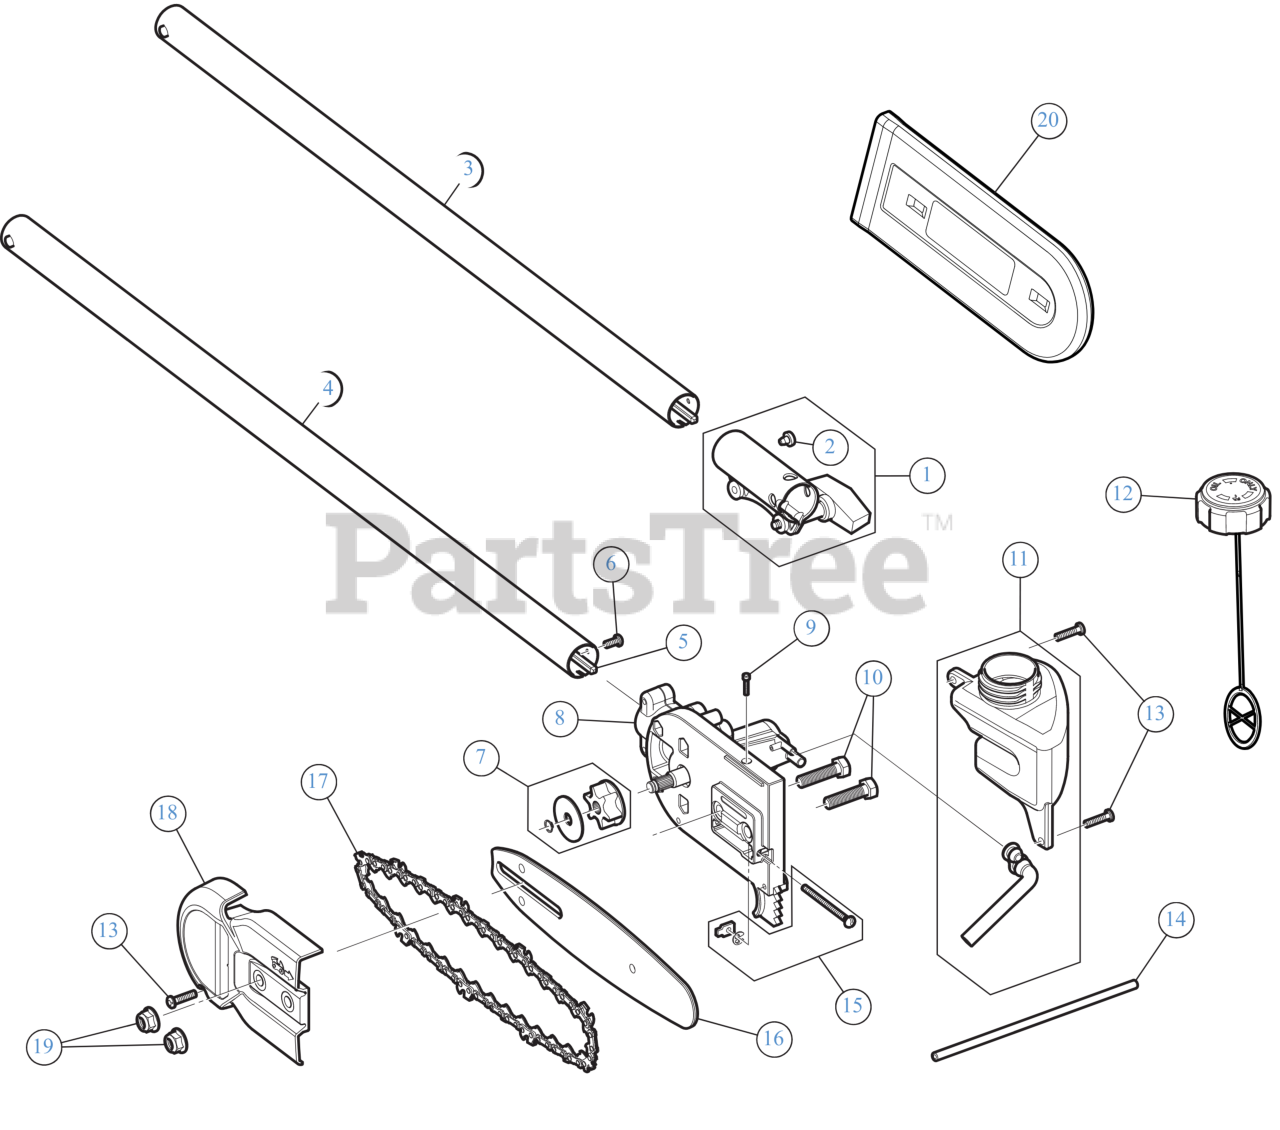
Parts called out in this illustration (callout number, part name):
1	SPLIT BOOM COUPLER KIT
2	SCREW, 10-32X.250 TA
3	EXTENSION BOOM ASSEMBLY
4	LOWER DRIVE SHAFT HOUSING
5	FLEXIBLE DRIVE SHAFT
6	SCREW 1/4-20 X.500
7	SPROCKET ASSEMBLY
8	GEAR BOX ASSEMBLY
9	SCREW 4X40X.50
10	SCREW 5/16-18 x 1.25 GR5
11	OIL TANK ASSEMBLY
12	FUEL CAP ASSEMBLY
13	SCREW, #8-16X.750 PH
14	OIL LINE
15	CHAIN TENSION HDW
16	BAR 8" SPROCKET NOSE
17	CHAIN 8" 34 LINK .043 GAUGE
18	CHAIN GUARD RED
19	FLANGE LOCK NUT 5/16-18
20	8" SCABBARD
